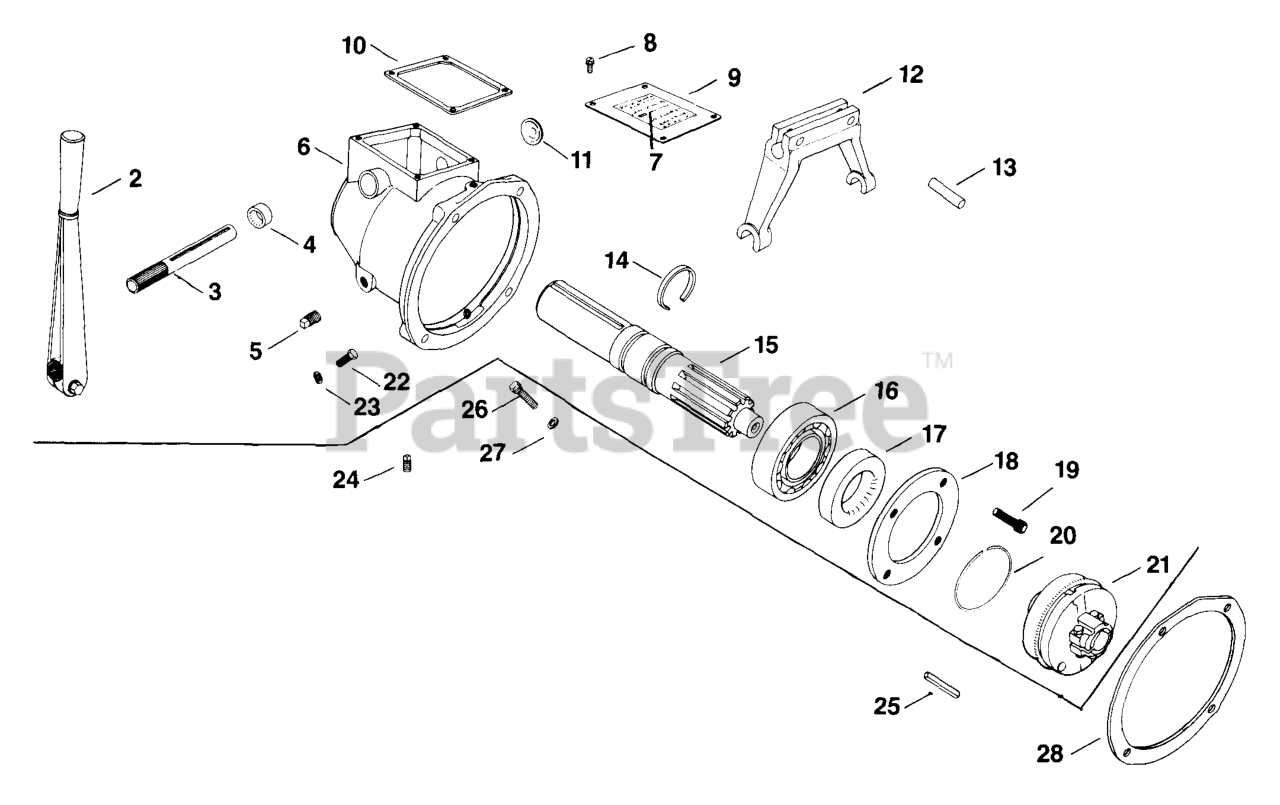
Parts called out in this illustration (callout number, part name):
2	LEVER - DISCONTINUED
3	SHAFT - DISCONTINUED
5	PLUG,PIPE 1/4 NPTF SQUARE HD USE 25 139 53-S
6	Housing, P.T.O.
6	HOUSING - DISCONTINUED
8	SCREW, SLT PAN HD 10-24X3/8" USE 25 086 60-S
9	COVER - DISCONTINUED
10	GASKET - DISCONTINUED
11	PLUG - DISCONTINUED
12	YOKE - USE 24 471 01
14	RING - DISCONTINUED
15	SHAFT - DISCONTINUED
16	BEARING - DISCONTINUED
18	PLATE - DISCONTINUED
20	RING, SNAP - DISCONTINUED
21	CLUTCH - DISCONTINUED
22	SCREW, CAP HD 3/8-16x1-1/4"-DISC.
23	WASHER, SPRING LOCK 3/8"
24	PLUG-DISCONTINUED
25	KEY - DISCONTINUED
26	SCREW, CAP HD 7/16-14x2"
27	WASHER, SPRING LOCK 7/16"
